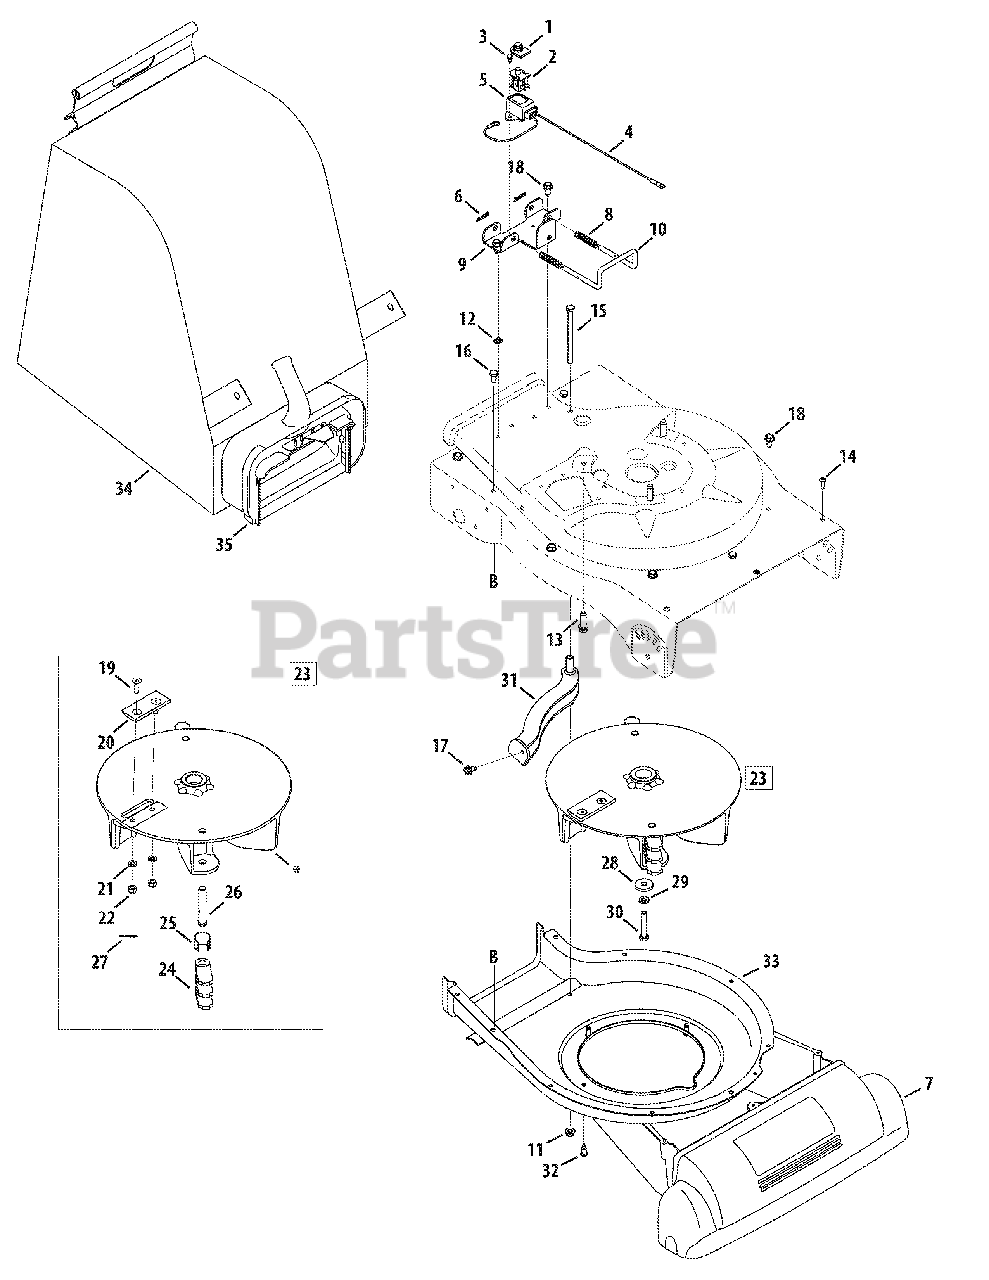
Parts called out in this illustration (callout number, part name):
1	Switch Cover
2	Safety Switch
3	Hex Washer Screw, #10-16 x.50
4	Wire Harness
5	Safety Switch Cover
6	Cotter Pin
7	Nozzle Cover
8	Compression Spring
9	Mounting Bracket
10	Lock Rod
11	Flange Lock Nut, 5/16-18
12	External Lock Washer 5/16
13	Hex Washer Screw 3/8-16 x 1.25
14	Screw, #12-16 x .750
15	Hex Cap Screw 5/16-18 x 4.5
16	Hex Cap Screw 5/16-18 x.625
17	Screw, 5/16-18 x.500
18	Screw, 5/16-12 x.75
19	Hex Screw 5/16-24 x 1.0
20	Chipper Blade
21	Lock Washer 5/16
22	Hex Lock Nut 5/16-24
23	Impeller Assembly
24	Flail Blade
25	Pin Clip
26	Clevis Pin
27	Spiral Pin
28	Flat Washer.375 ID x 1.25 OD
29	Lock Washer 3/8
30	Hex Cap Screw 3/8-24 x 2.0
31	Screen Assembly
32	Shoulder Screw, .30 x .46
33	Lower Housing
34	Bag Assembly
35	Chute Assembly
